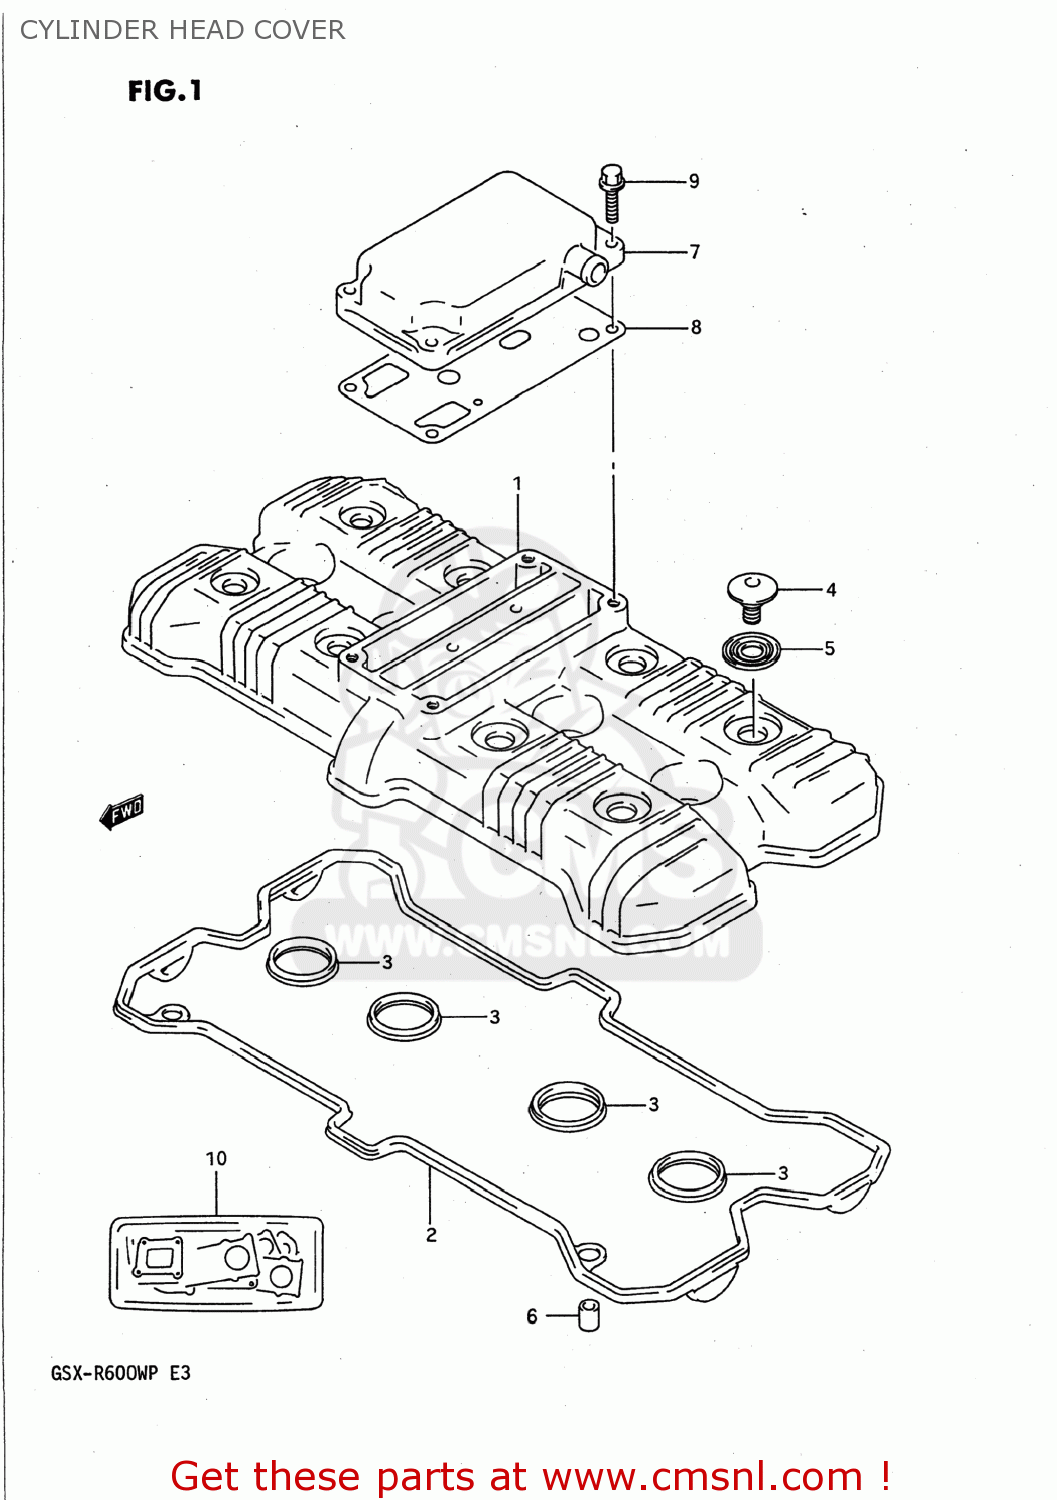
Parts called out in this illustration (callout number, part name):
1	COVER,CYLINDER HEAD
2	GASKET,CYL HEAD COVER NO.1
3	GASKET,CYL HEAD COVER NO.2
4	BOLT(7X17.5)
5	WASHER(10.6X25.5X2.3)
6	PIN(6.2X8X11)
7	COVER,BREATHER
8	GASKET,BREATHER COVER
9	BOLT 6X25
10	GASKET SET (NAS)
